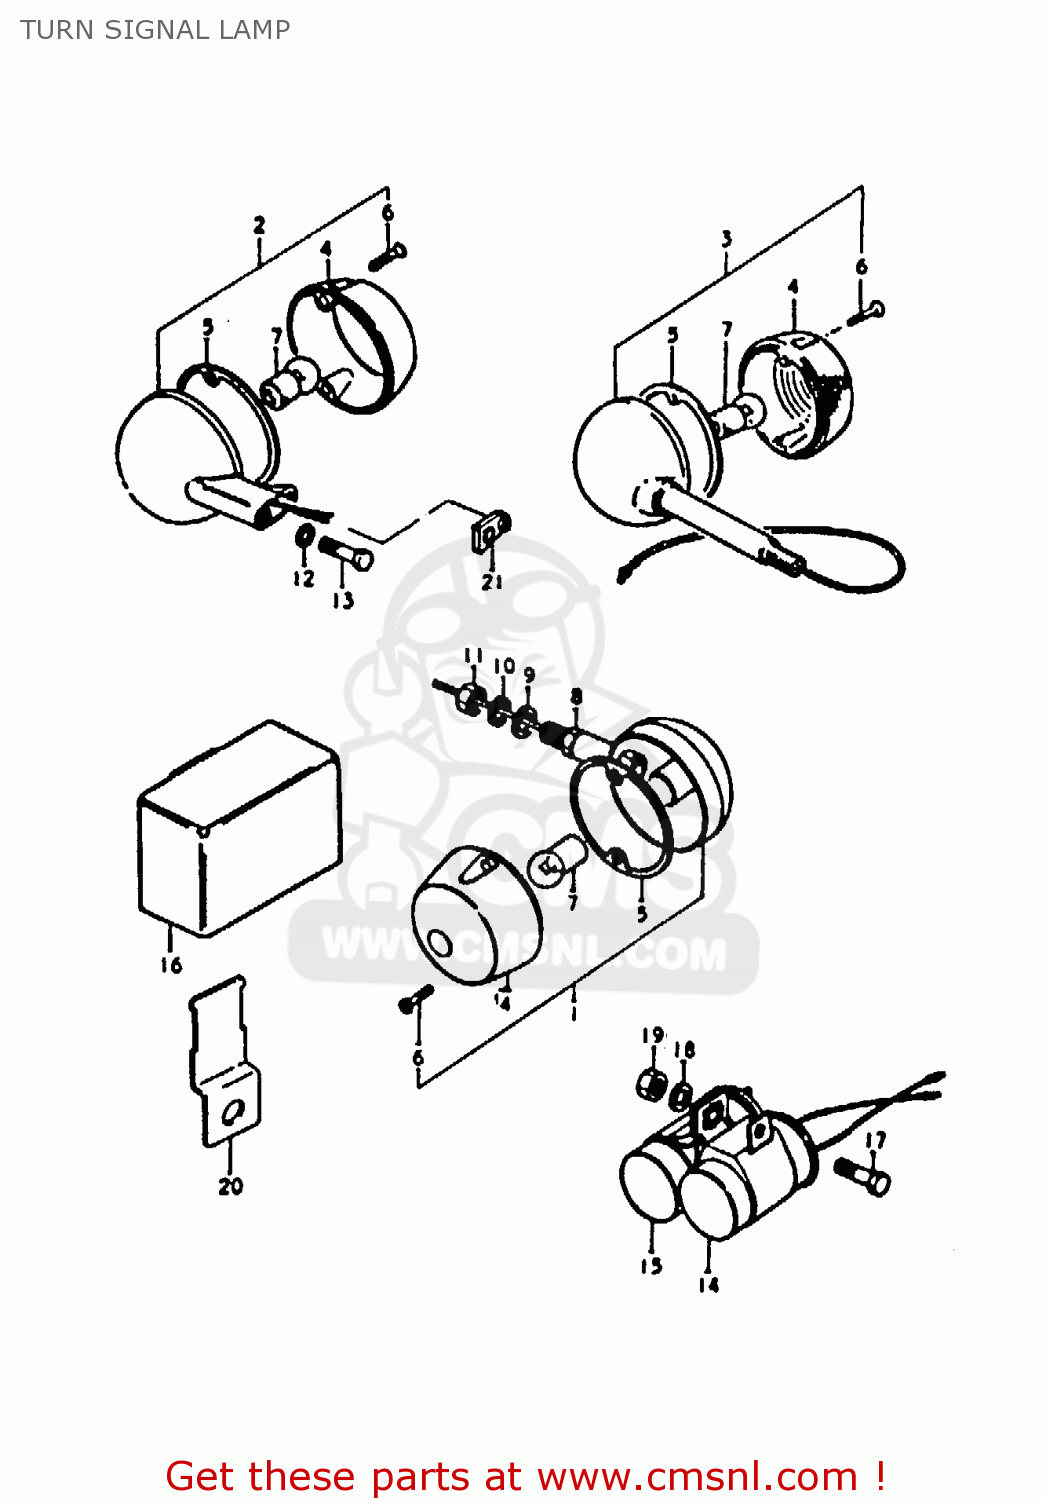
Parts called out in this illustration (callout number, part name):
1	LAMP ASSY, TURN SIGNAL FRONT
2	LAMP ASSY,RR TURNSIGNAL
4	LENS
5	GASKET (NAS)
6	SCREW
7	BULB(6V8W,STANLEY,A4115)
9	WASHER
10	LOCK WASHER
11	NUT
12	LOCK WASHER
13	BOLT
14	RELAY, TURN SIGNAL
17	BOLT
18	WASHER
19	NUT
